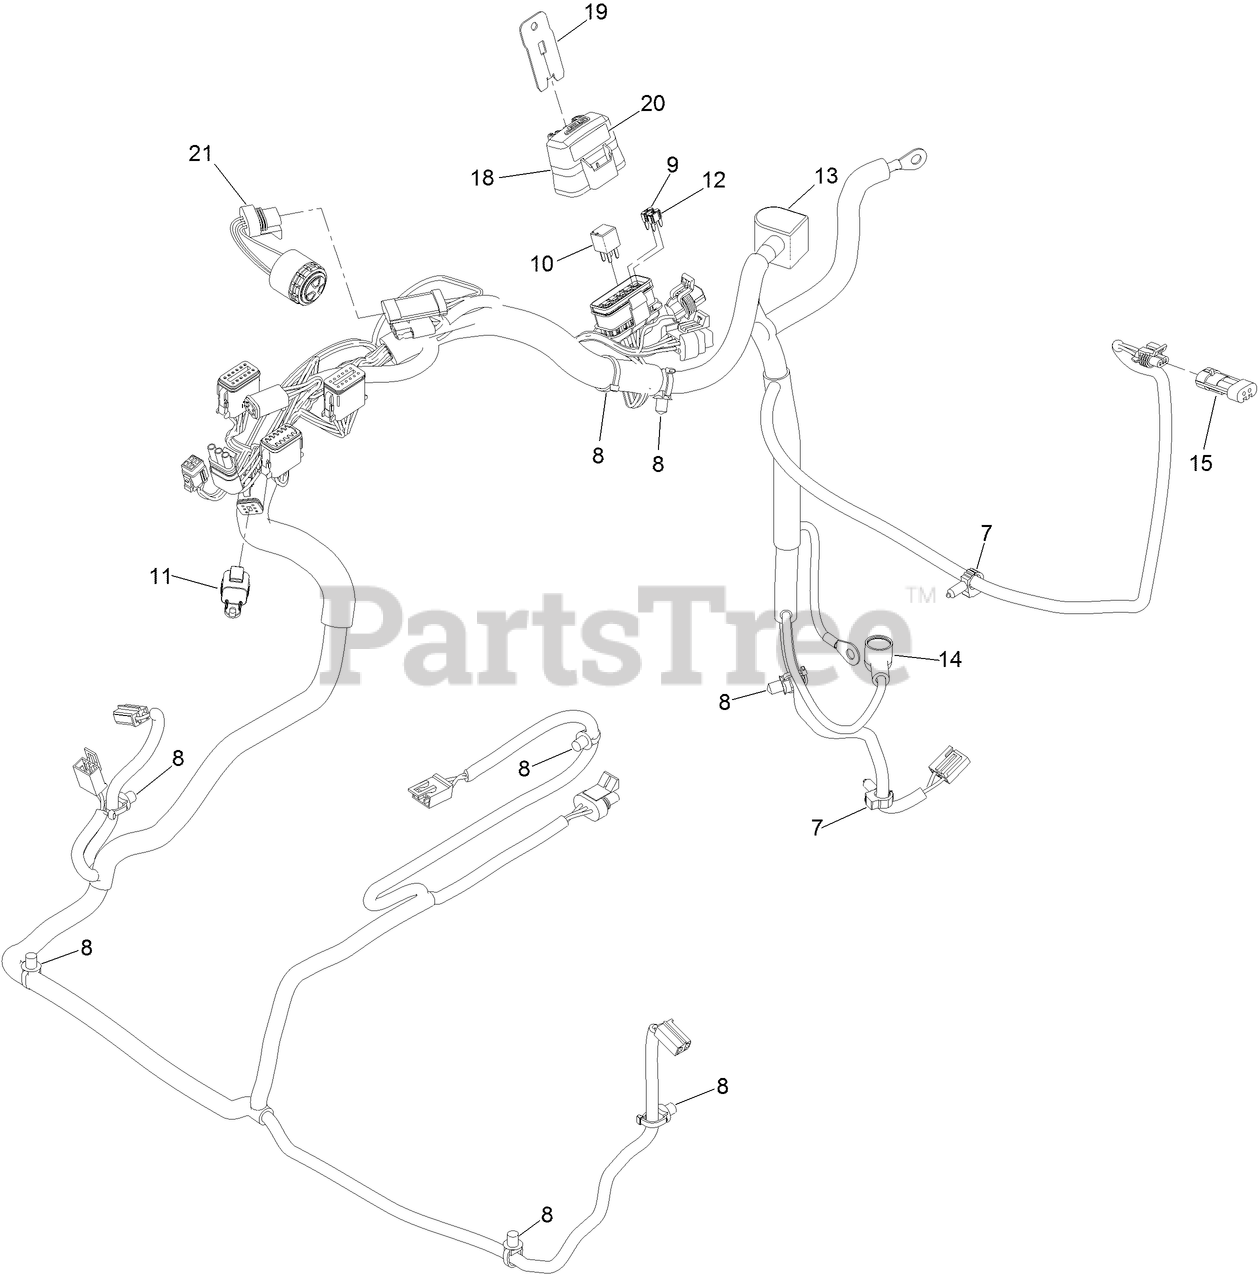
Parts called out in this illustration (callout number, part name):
7	CLIP-HARNESS
8	CLIP-TIE
9	FUSE-MINI BLADE, 20 AMP
10	RELAY-MICRO
11	CAP-PLUG, 6 WAY
12	FUSE-MINI BLADE, 15 AMP
13	INSULATOR-BATTERY
14	INSULATOR-SOLENOID
15	CONNECTOR
18	COVER-BLOCK, FUSE
19	CLIP-MOUNTING
20	DECAL-FUSE
21	ALARM-DUAL TONE
